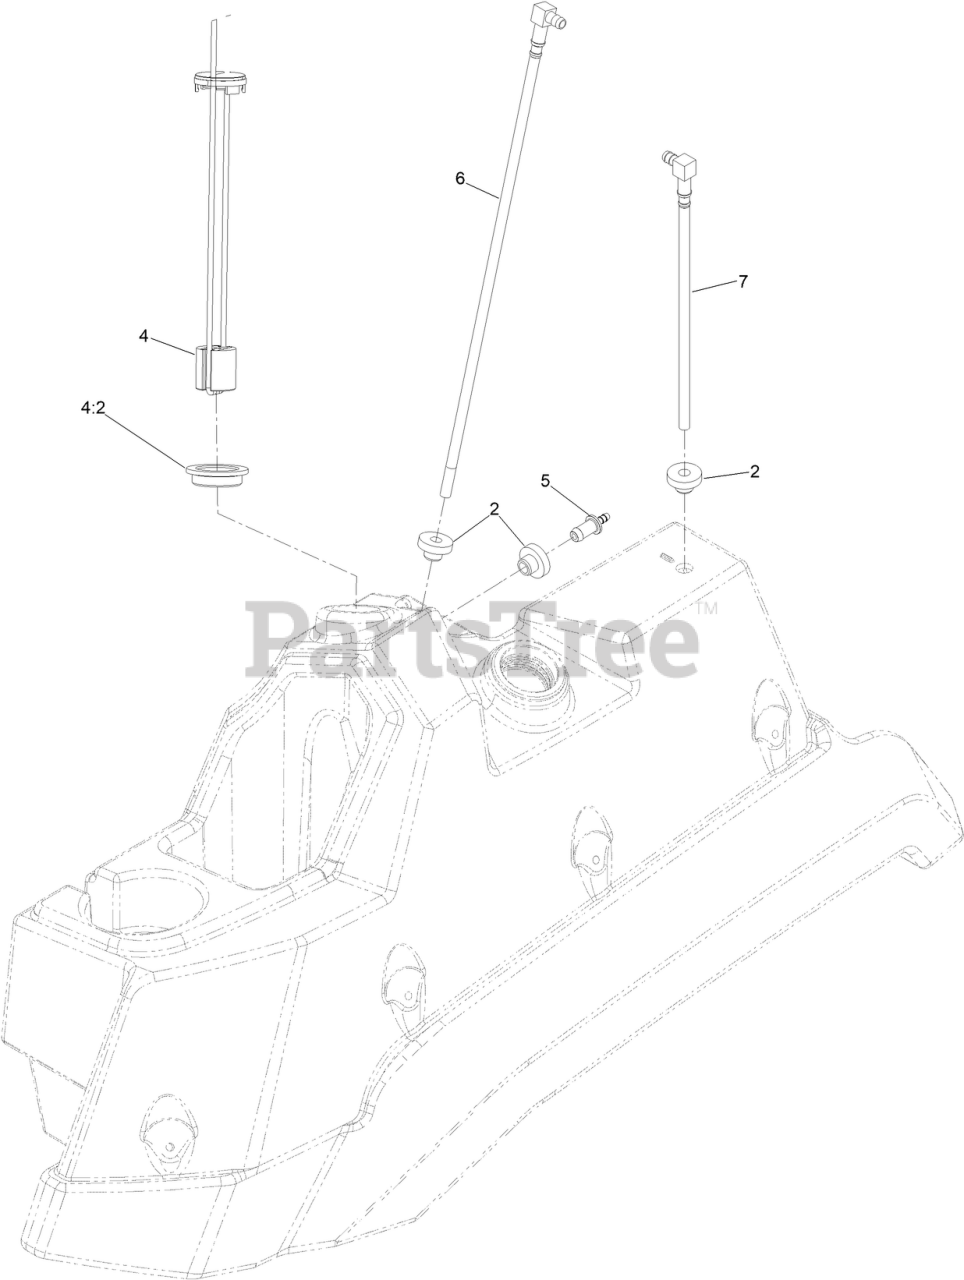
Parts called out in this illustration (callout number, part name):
2	BUSHING
4	GAUGE-FUEL
4:2	SEAL-FUEL GAUGE
5	FITTING-ORIFICE, STRAIGHT
6	PICK-UP-FUEL
7	RETURN-FUEL
